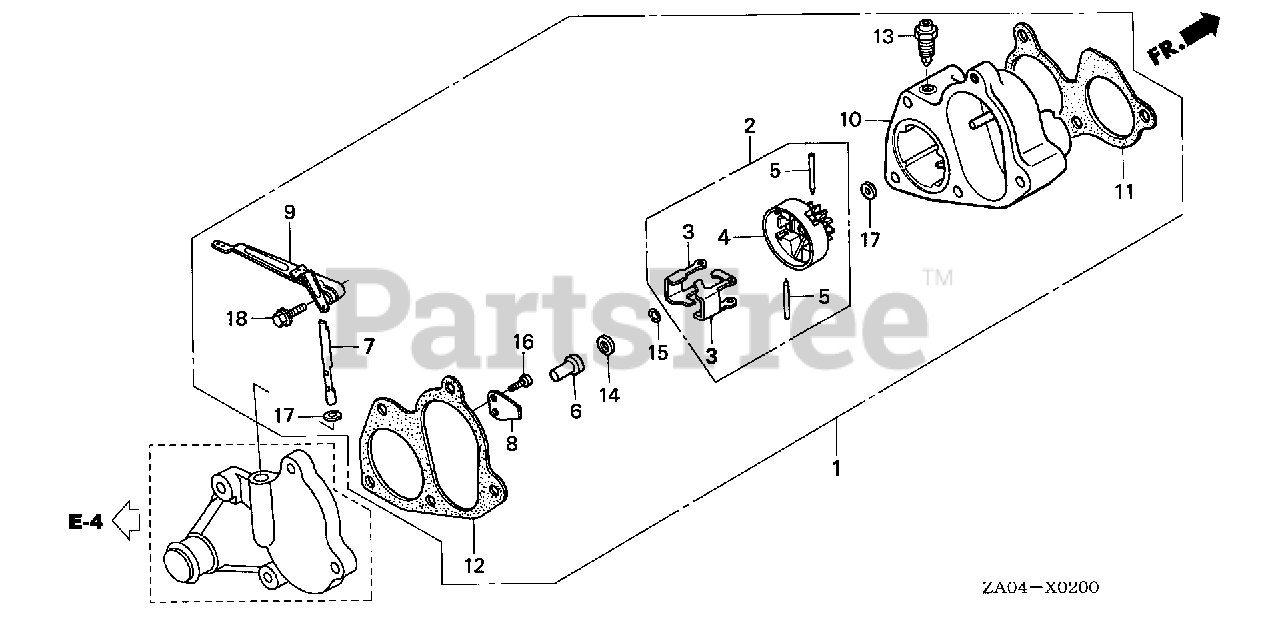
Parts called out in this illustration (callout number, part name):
1	GOVERNOR KIT (EL/ES) (NOT AVAILABLE)
2	GOVERNOR ASSY. (NOT AVAILABLE)
3	WEIGHT, GOVERNOR
4	HOLDER, GOVERNOR WEIGHT
5	PIN, GOVERNOR WEIGHT
6	SLIDER, GOVERNOR (NOT AVAILABLE)
7	SHAFT, GOVERNOR ARM (NOT AVAILABLE)
8	FORK, GOVERNOR
9	ARM, GOVERNOR (NOT AVAILABLE)
10	CASE, GOVERNOR
11	GASKET, GOVERNOR CASE
12	GASKET, THERMOSTAT COVER (NOT AVAILABLE)
13	BOLT, BREATHING WATER
14	WASHER, THRUST (6MM)
15	CLIP, GOVERNOR HOLDER
16	SCREW, PAN (3X6)
17	WASHER, PLAIN (6MM)
18	BOLT, FLANGE (6X20)
